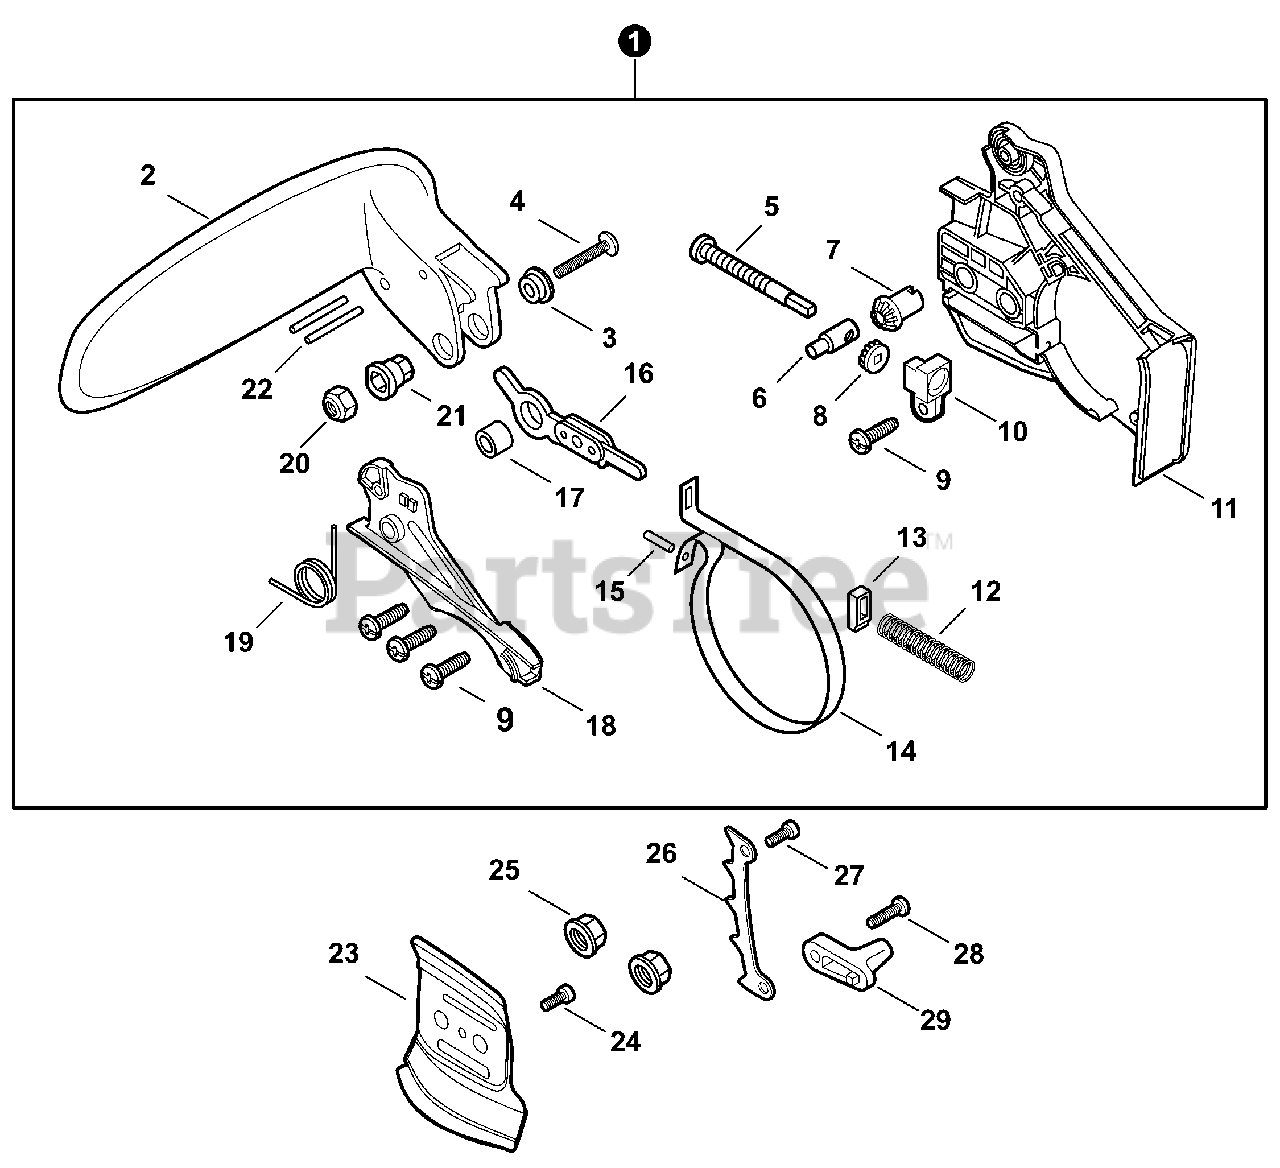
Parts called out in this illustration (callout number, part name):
1	BRAKE ASSY, CHAIN
2	LEVER, BRAKE - BLACK
3	COLLAR 5.3×10×13×L5
4	SCREW 5×32
6	TENSIONER, CHAIN
7	GEAR, BEVEL
8	GEAR, BEVEL
9	SCREW 4×12
10	COLLAR 8
11	GUARD, SPROCKET - ORANGE
12	SPRING, COMPRESSION
14	BAND, BRAKE
15	PIN, SPRING 3×9.8
16	CONNECTOR, BRAKE
17	SPACER 8×12×9
18	COVER, BRAKE - ORANGE
19	SPRING, TORSION
20	NUT, LOCK M5
21	COLLAR 5
22	PIN 3×26
23	PLATE, GUIDE - INNER
24	SCREW 4×10
25	NUT, FLANGE 6
26	SPIKE, BUMPER
27	SCREW 5×20
28	SCREW 5×20
29	CHAIN CATCHER
